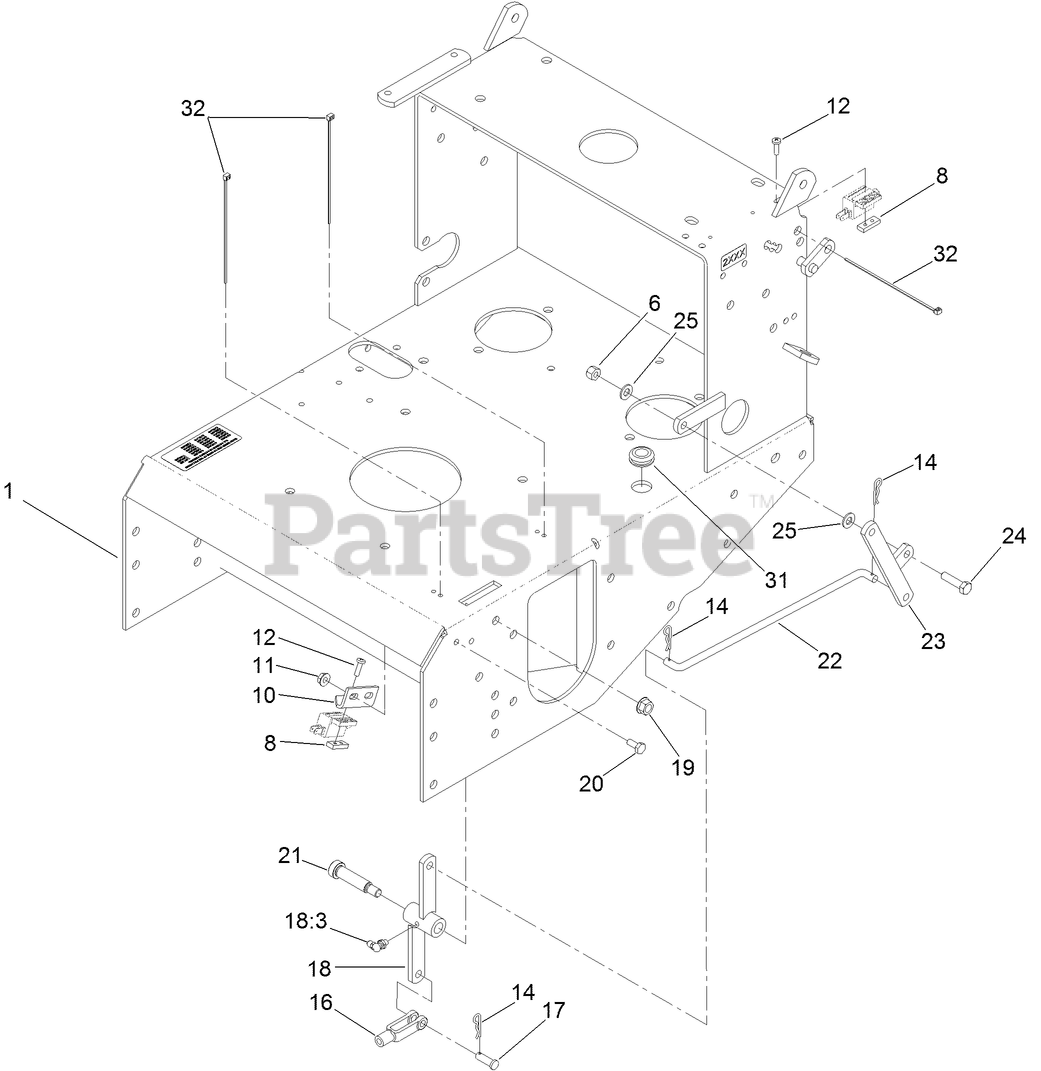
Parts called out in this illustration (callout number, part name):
1	HYDRO FRAME ASM
6	NUT-LOCK, NI
8	PLATE-TAPPED
10	Bracket-Switch, Blade
11	NUT-HF
12	SCREW-PPH
14	PIN-COTTER
16	YOKE-ADJUSTABLE
17	PIN-CLEVIS
18	Bellcrank ASM
18:3	FITTING-GREASE, 90 DEG
19	NUT-HF
20	SCREW-HH
22	Linkage-Engage, Blade
23	BELLCRANK ASM
24	SCREW-HH
25	WASHER-PLAIN
31	GROMMET
32	TIE-CABLE
